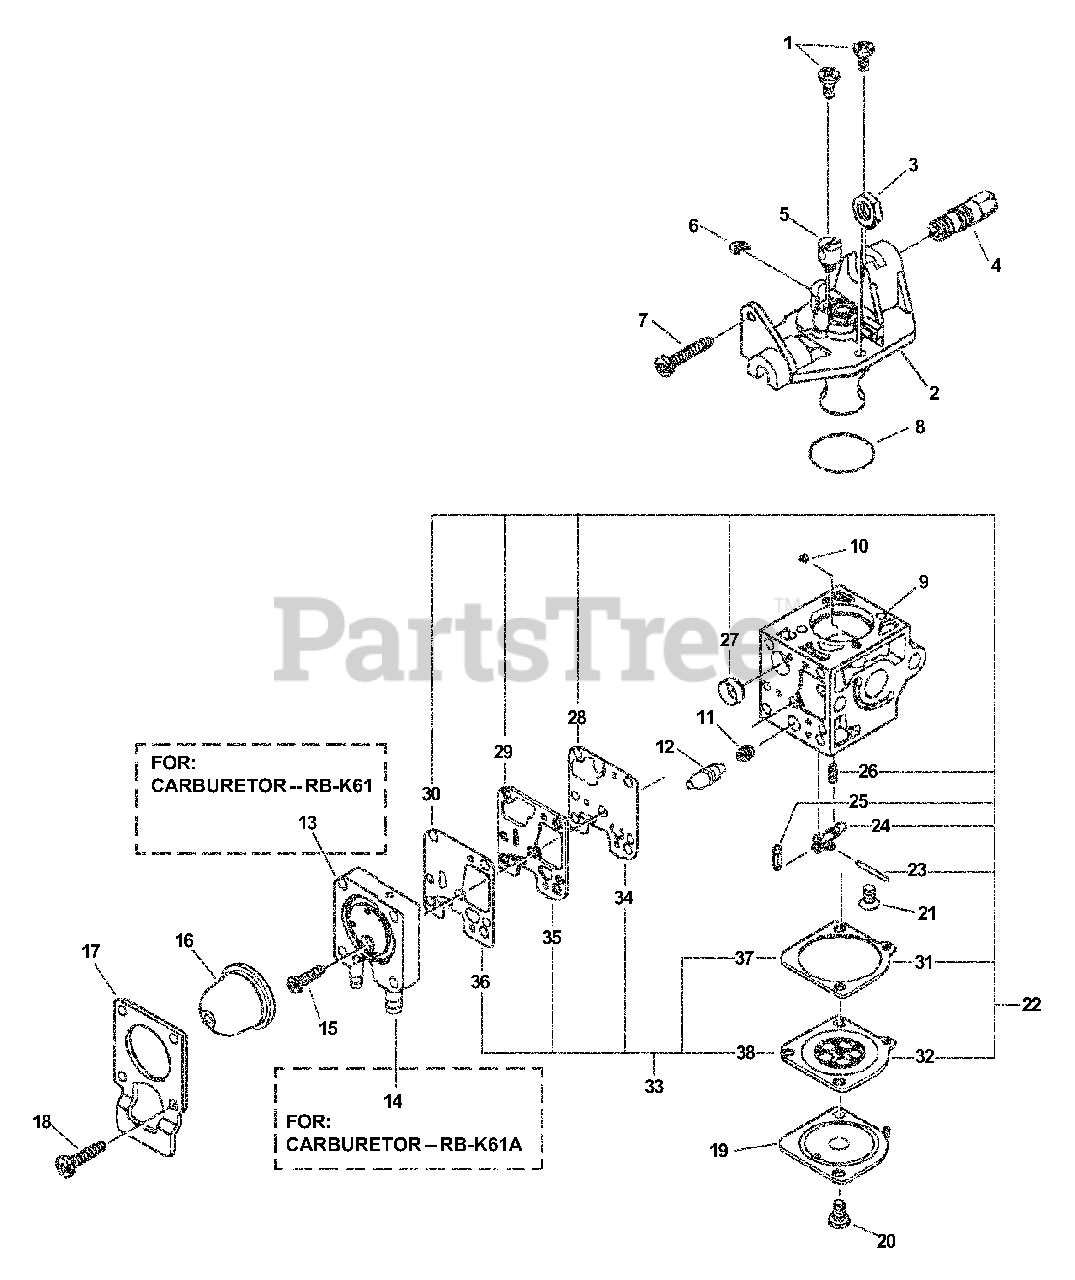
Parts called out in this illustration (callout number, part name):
2	ROTOR COVER ASSY
4	NUT, CABLE ADJUST
6	RING, RETAINING
7	SCREW, IDLE ADJUST
9	BODY, CARBURETOR
10	GUIDE, ROLLER
12	PLUG KIT
13	BASE, PURGE
14	BASE, PURGE
15	SCREW, PURGE BASE
16	BULB, PURGE
17	RETAINER, PURGE BULB
18	SCREW, RETAINER
19	COVER, METERING
21	SCREW, METERING LEVER PIN
22	REPAIR KIT
23	PIN, METERING LEVER
24	LEVER, METERING
25	VALVE, INLET NEEDLE
26	SPRING, METERING LEVER
27	STRAINER
28	DIAPHRAGM, PUMP
29	GASKET, PUMP
30	SURGE, DIAPHRAGM
31	GASKET, METERING
32	DIAPHRAGM, METERING
33	DIAPHRAGM/GASKET KIT
34	DIAPHRAGM, PUMP
35	GASKET, PUMP
36	SURGE, DIAPHRAGM
37	GASKET, METERING
38	DIAPHRAGM, METERING
